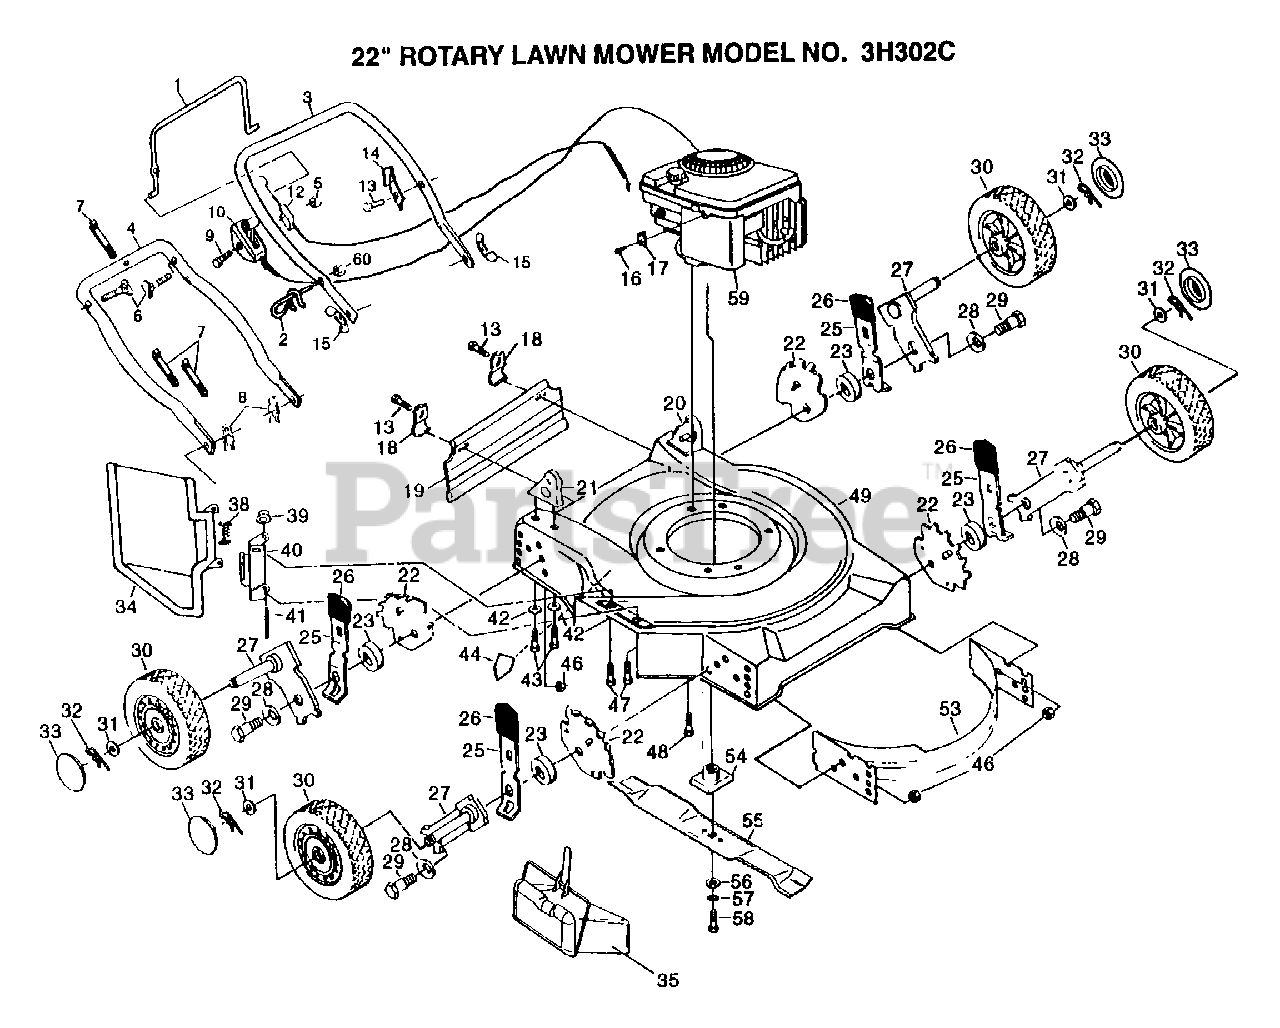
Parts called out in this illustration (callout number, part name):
1	CONTROL BAR
2	ROPE GUIDE
6	BOLT.HANDLE.LM
8	HAIRPIN COTTER
9	SCREW.HXHD.WASH.
10	"CONTROL, THROTTLE"
12	"CABLE,ENG ZONE CO"
13	TAPPING SCREW
14	"BRKT,UPSTOP"
15	"NUT,WING PM"
16	SCREW PM
17	CABLE CLAMP
18	"BRKT,DEFL PM"
19	SKIRT.REAR.FGD.22
22	BRACKET.ADJ.9POS.
25	SPRING SELECTOR
26	KNOB PM
27	AXLE ARM
28	"WASHER, BELLEVIL."
29	BOLT SHLD 3/8-16
31	WASHER
32	RETAINER CLIP PM
33	HUB CAP
35	PLUG.MULCHING.ASM
37	LOCKNUT
38	"SPRING,TORSION"
39	PUSH ON SPEED NUT
40	"BRKT,HSG"
41	"ROD,HINGE "
42	STEEL WASHER
43	SCREW
44	DECAL HYT
46	LOCKNUT PM
47	SCREW
48	SCREW
49	KIT.HSG.22SD.PUSH
53	BAFFLE.FRT/REAR
54	BLADE ADAPTOR
56	WASHER (HARDENED)
57	LOCKWASHER
58	SCREW
60	NUT
